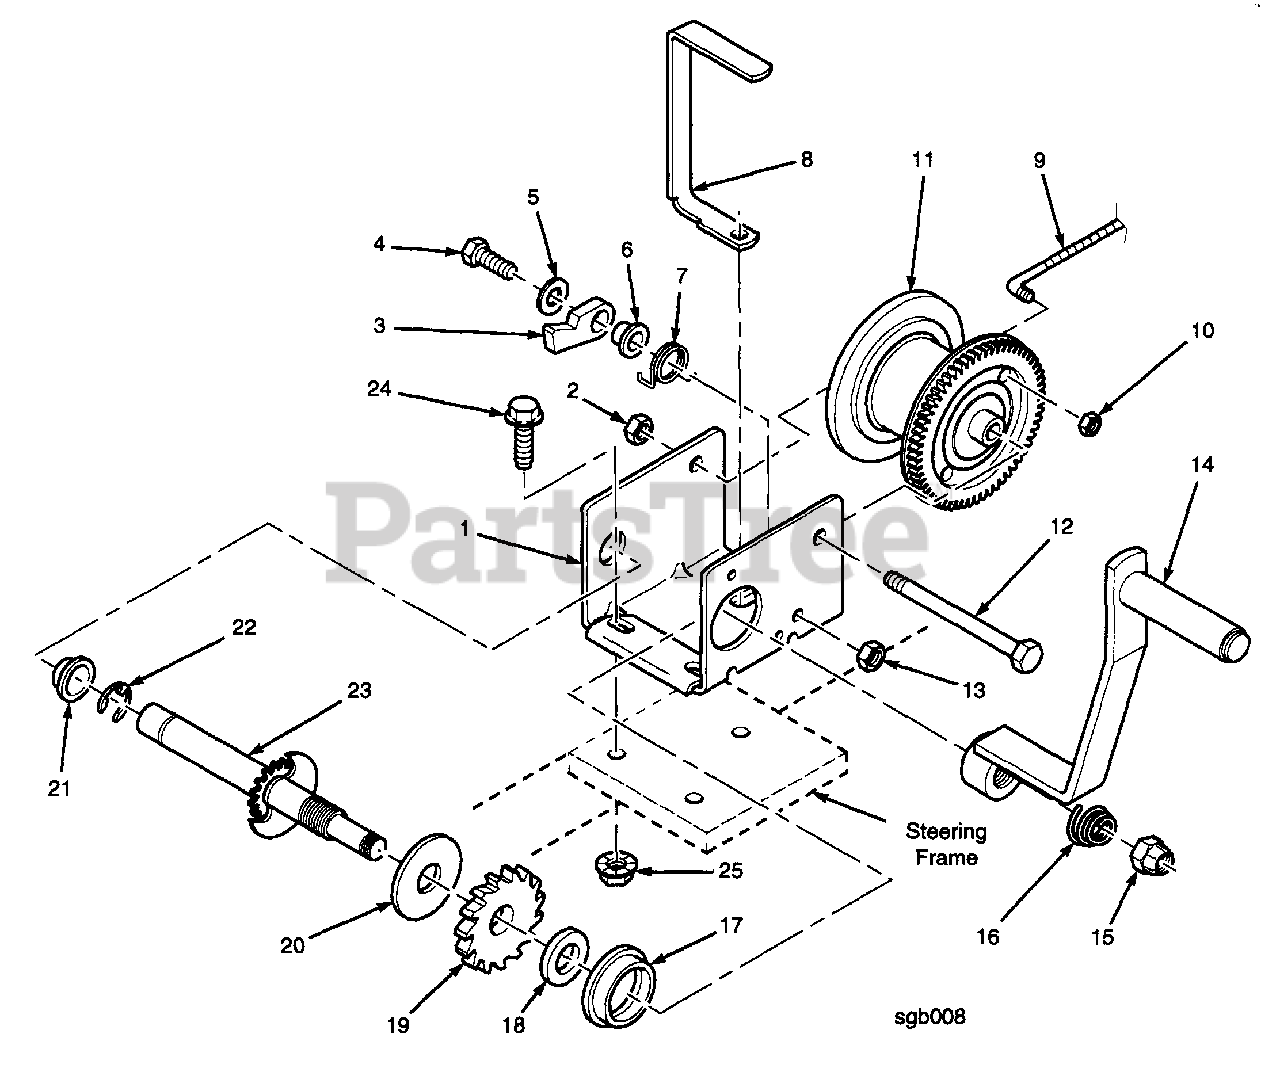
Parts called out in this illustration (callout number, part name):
1	WINCH ASSEMBLY(INCL. 1-7, 11-23)
2	LOCKNUT, 7/16-14
3	RATCHET PAWL
4	RATCHET BOLT
5	FLATWASHER
6	RATCHET SPACER
7	RATCHET SPRING
8	CABLE GUIDE
9	WINCH CABLE ASSEMBLY
10	HEX LOCKNUT, 1/4-28
11	WINCH REEL
12	REEL SHAFT
13	HEX LOCKNUT, 3/8-16
14	WINCH HANDLE
15	HANDLE NUT
16	HANDLE SPRING
17	SHAFT BUSHING
18	PRESSURE WASHER
19	RATCHET WHEEL
20	PRESSURE PLATE
21	SHAFT BUSHING
22	E-RING
23	DRIVE SHAFT
24	SERR. FLG HH CPSCR, 3/8-16 X 1
25	SERR. FLG HH NUT, 3/8-16
